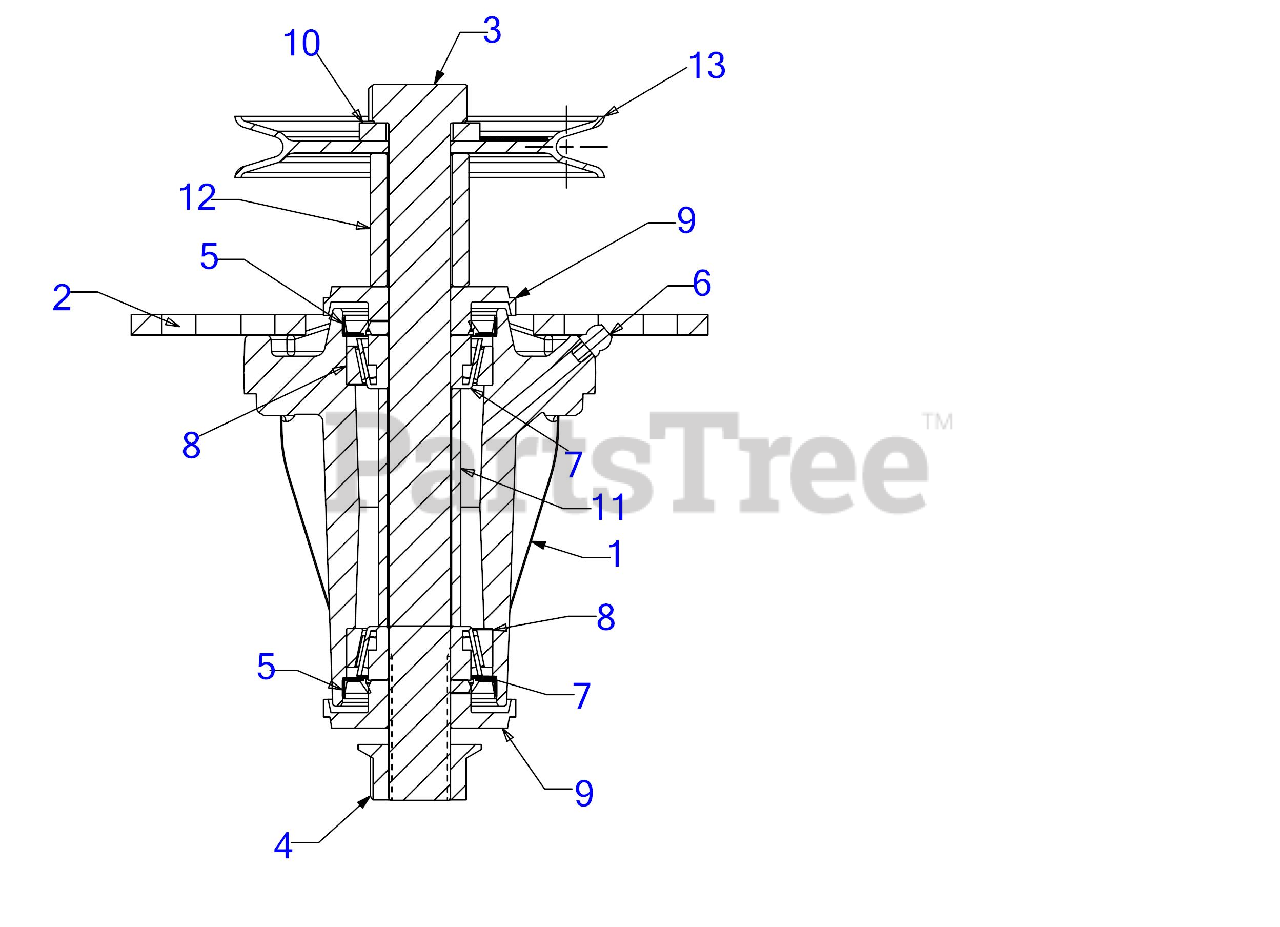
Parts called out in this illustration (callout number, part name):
1	HOUSING
3	SCREW 3/4-16 x 8.25 GR5
4	HEX FLANGE NUT 3/4
5	SINGLE LIP SEAL
6	GREASE FITTING
7	BEARING CONE
8	BEARING CUP
9	DECK SPINDLE SPACER
10	SPACER .812 ID x .218 LG
13	PULLEY-4.00 OD
